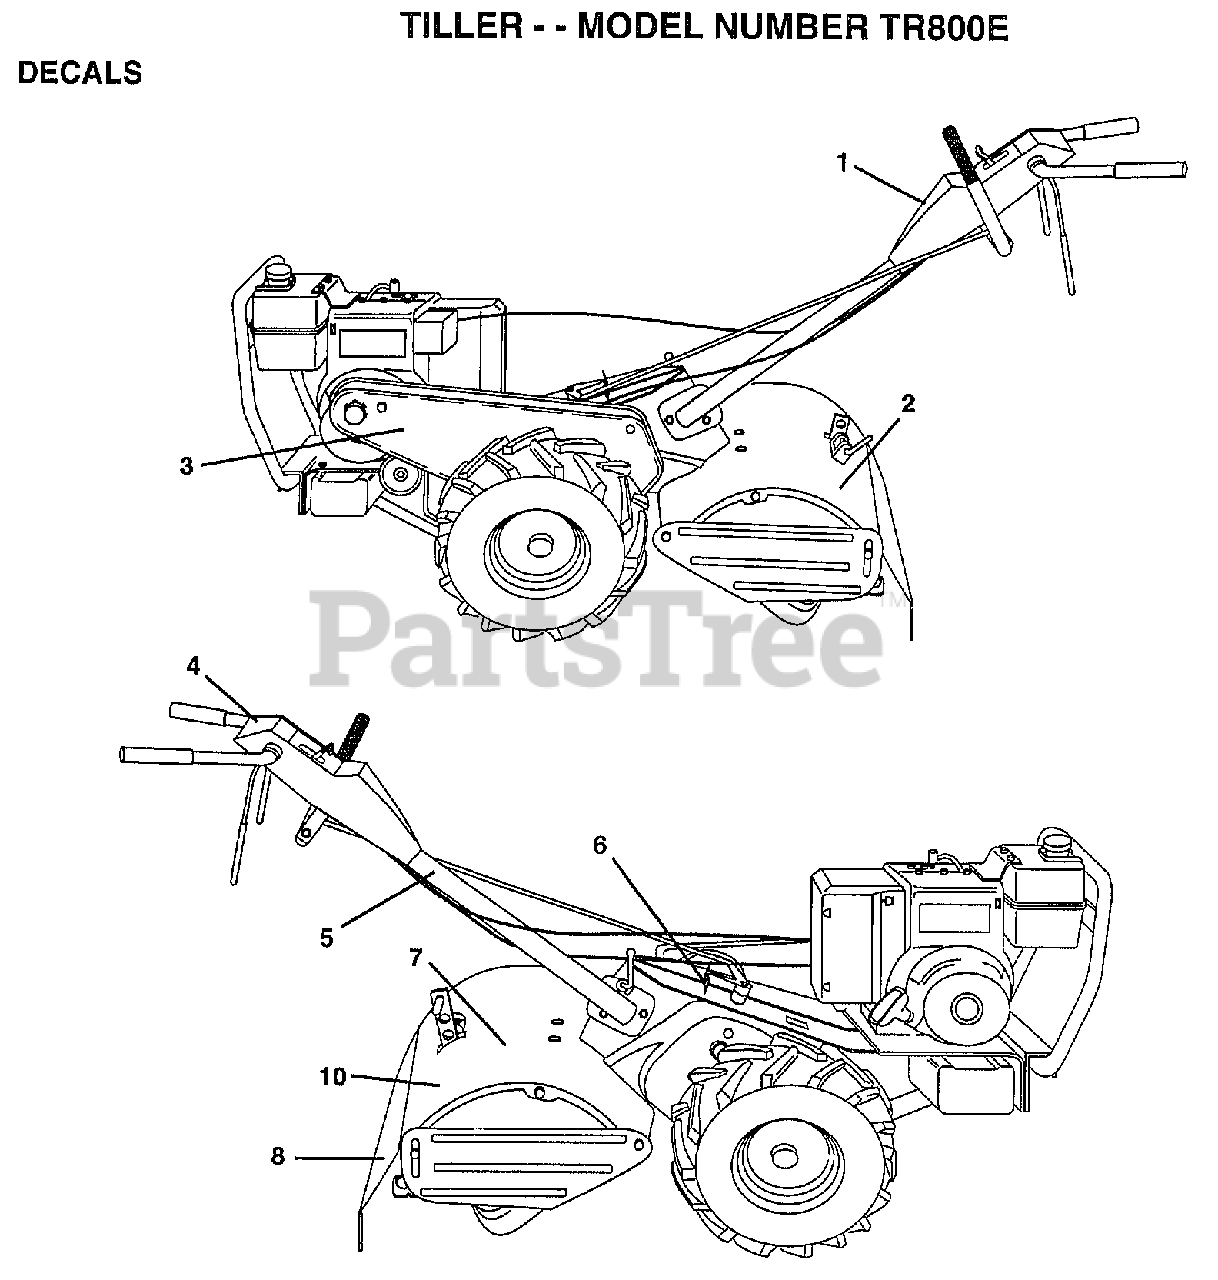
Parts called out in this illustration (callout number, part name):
1	DECAL.PNL.CONTROL
2	DECAL.SHLD.TINE
3	DECAL.GRD.BELT
4	DECAL.INST.PNL.CT
5	DECAL TI
6	DECAL.SHIFT.IND.
8	DECAL TI
10	DECAL.TINE.SHIELD
